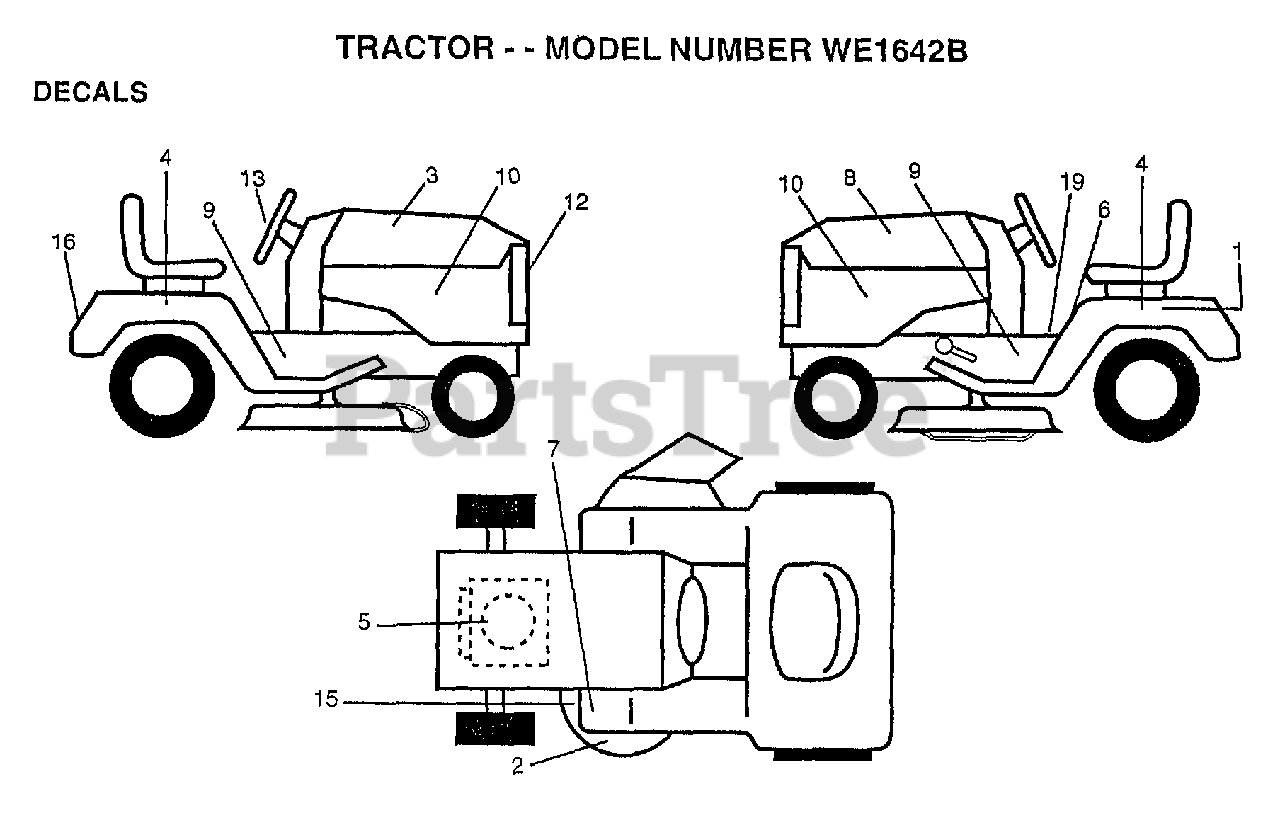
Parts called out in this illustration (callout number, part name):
1	DECAL.BATRY.3-3908
3	"DECAL HOOD,RH"
4	DECAL.FENDER.WIZ
5	DECAL, HP ENGINE
6	"DECAL DANGER,FEND"
8	DECAL HOOD LH
10	"DECAL PANEL,SIDE"
12	"DECAL GRILLE,LENS"
13	"DECAL INS,STRG WH"
15	DECAL
16	DECAL-FENDER
19	"DECAL INST,SADDLE"
